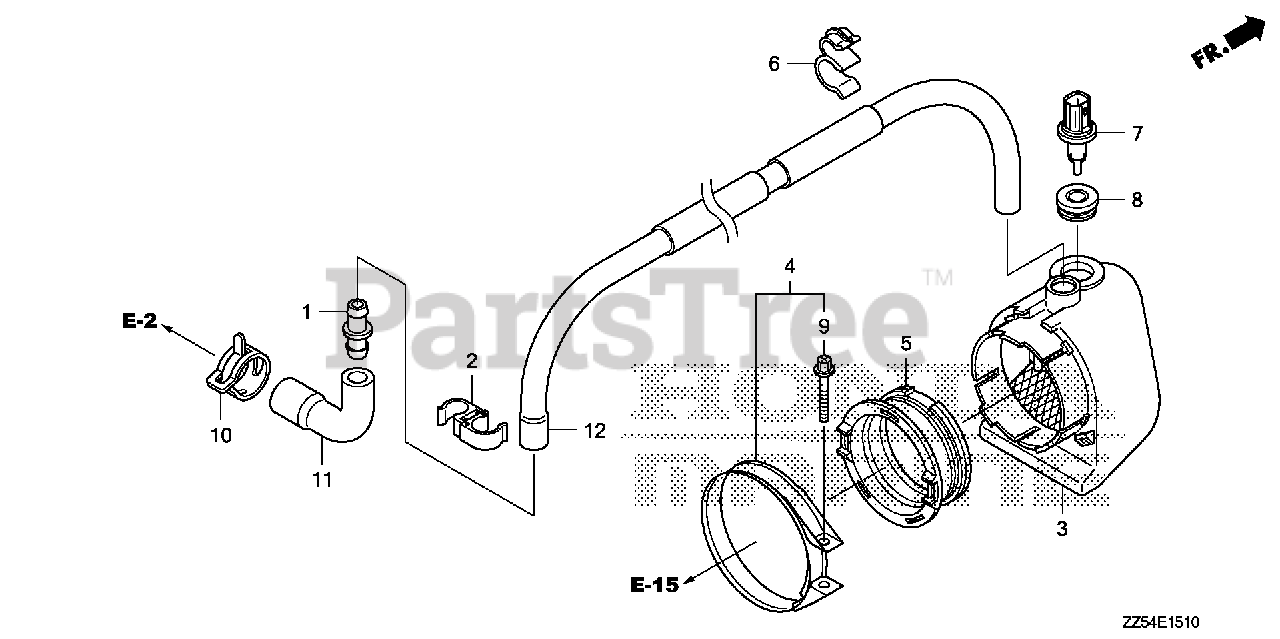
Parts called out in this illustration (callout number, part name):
1	JOINT, HOSE
2	CLAMP A, FUEL TUBE
3	GUIDE, AIR INLET
4	BAND, AIR FLOW
5	GROMMET, AIR GUIDE
6	CLAMP, TUBE (7.5-11.5) (BLACK)
7	SENSOR ASSY., AIR TEMPERATURE (MATSUSHITA DENSHI)
8	GROMMET, TA SENSOR
9	BOLT, CLAMP (4X35)
10	CLAMP, TUBE (D17)
11	TUBE A, BREATHER
12	TUBE B, BREATHER
